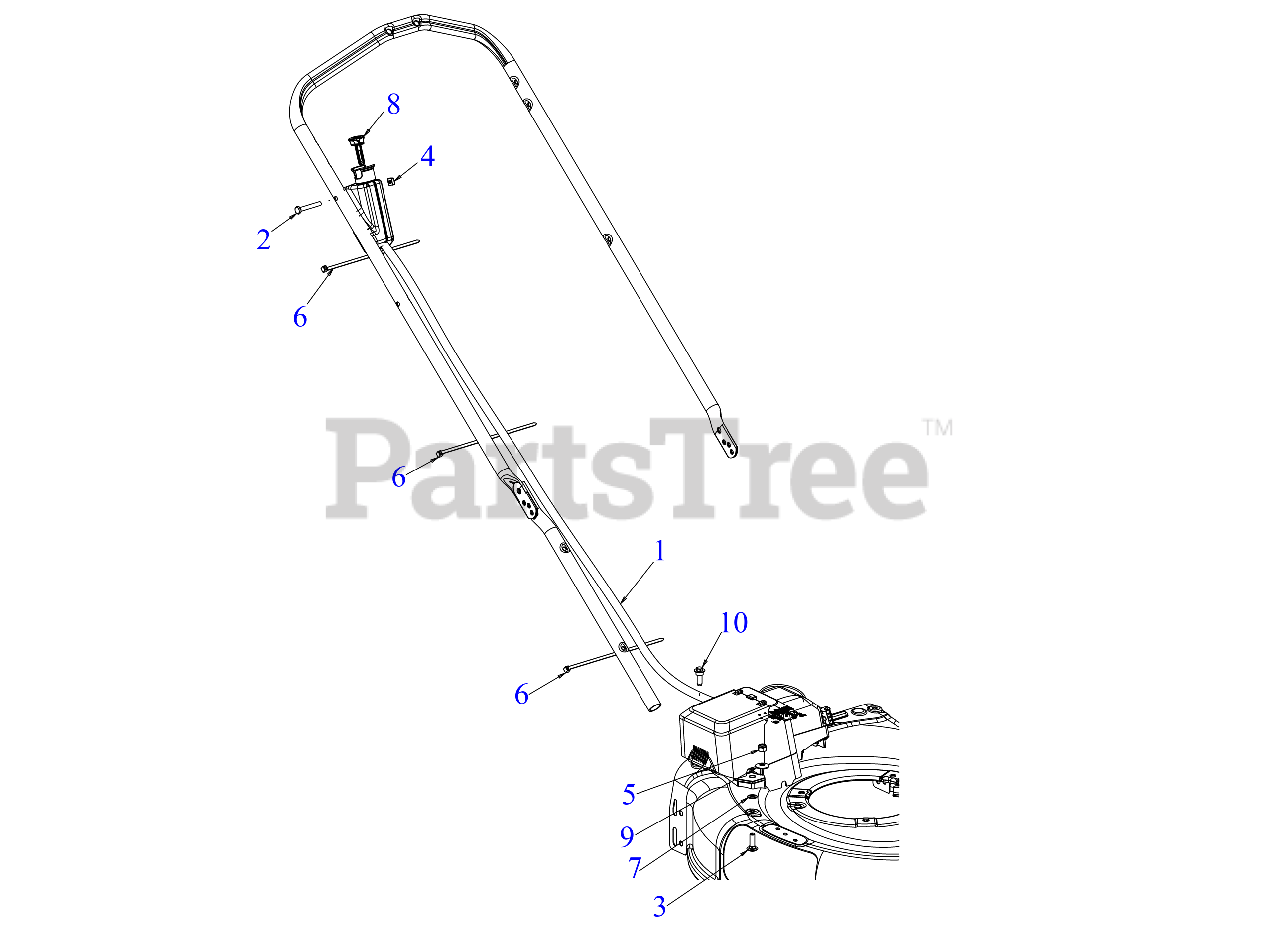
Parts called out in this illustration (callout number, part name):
2	HEX SCREW 1/4-20 x 1.75
3	CARRIAGE BOLT 5/16-18 x 1.00
4	SQUARE NUT 1/4-20
5	HEX NUT INS
6	7" CABLE TIE
7	PUSH NUT
8	PUSH KEY
9	BELL WASHER .337 X.867 x .057
10	SHOULDER SCREW 5/16-14 x .972
